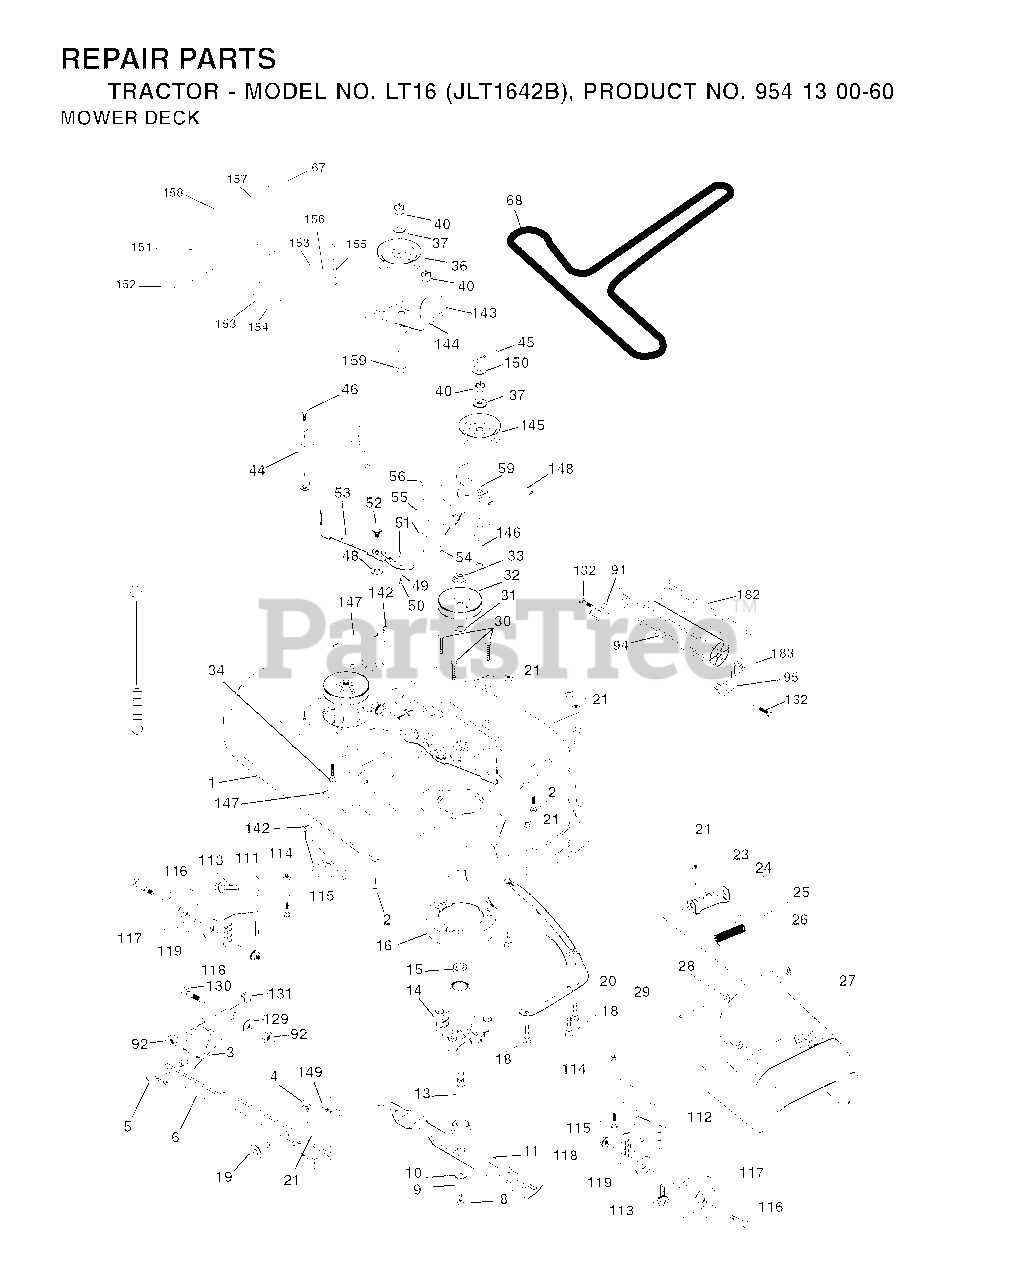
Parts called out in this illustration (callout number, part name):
1	42" DECK KIT
2	BOLT
3	BRKT ASM SWAY BAR
4	BRACKET SWAY BAR 42" DECK
5	RETAINER-SPRNG RB
6	BAR SWAY DECK
8	BLADE BOLT
9	LOCKWASHER
10	WASHER.BLADE
11	BLADE 42"
13	SHAFT ASM VENT
14	HSG MANDREL
16	STRIPPER, MWR ROUND
18	BOLT
19	BOLT SHD 5/16-18
20	BAFFLE.VORTEX
21	LOCKNUT
23	BRKT, DEFL. MOWER
24	CAP-SLEEVE LT
25	SPRING TORSION
26	NUT PUSH M
27	SHIELD DEFLECTOR
28	WASHER
29	ROD.HINGE
30	SCREW, WASHER HEAD
31	WASHER
32	PULLEY/MANDREL
33	NUT, FLG TOPLOCK 9/16"
34	BOLT
36	FLAT IDLER PULLEY
40	LOCKNUT
44	GUARD MANDREL LH BLACK
45	RETAINER M
46	SCREW.1/4-20X5/8
49	ROLLER ASM CAM FOLLOWER
50	BOLT
53	ARM
54	HARDENED WASHER
55	ARM IDLER 42" MOWER LT/YT
56	SPACER.RETAINER.MOWER
59	GUARD, BELT
67	KNOB T (3/8 HOLE)
91	BRACKET ASM NOSEROLLER LH
92	NUT
94	NOSE ROLLER
95	BRACKET ASM NOSEROLLER RH
111	BRACKET, WHEEL
112	BRACKET, WHEEL
113	SCREW.3/8-16X.625
114	NUT
115	BOLT
117	WHEEL.GAUGE.STANDARD
118	LOCKNUT
119	WASHER
129	WASHER
131	BOLT D
132	SCREW 3/8-16X3/4
142	ARM SPRING BRAKE MOWER
143	BRACKET, ARM IDLER
144	KEEPER.BELT.42".CLUTCH.CABLE
145	PULLEY
146	BOLT, CARRIAGE IDLER BLACK
148	IDLER RETURN SPRING
149	SPRING.RETAINER.YELLOW.ZINC
150	WASHER PM
151	BRACKET, CLUTCH CABLE
152	42" CLUTCH CABLE
153	WASHER FLAT 3/8"
154	SPRING RETAINER
155	SPRING RETENTION LEVER
156	SPACER CLUTCH CABLE
157	ROD CLUTCH CABLE 3/8"
158	SCREW
159	BOLT
182	ROD ROLLER NOSE STANDARD
183	SPRING RETAINER
